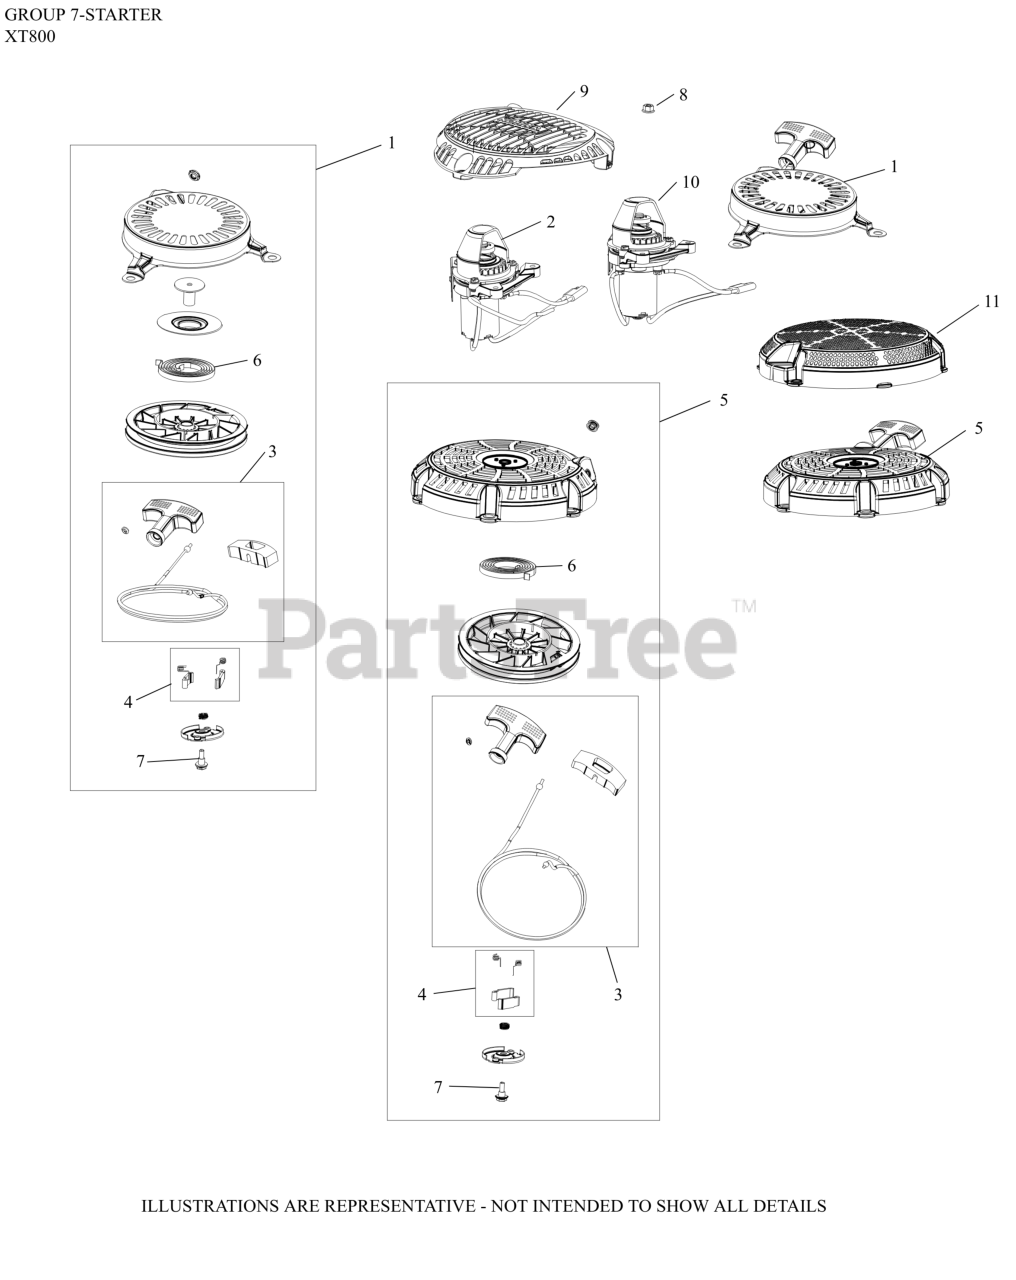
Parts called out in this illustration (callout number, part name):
3	KIT, STARTER ROPE W/HANDLE
4	KIT, PAWL REPAIR
5	STARTER ASSY-RETRACT-USE 14 165 21-S
7	SCREW, SHOULDER (M5)
